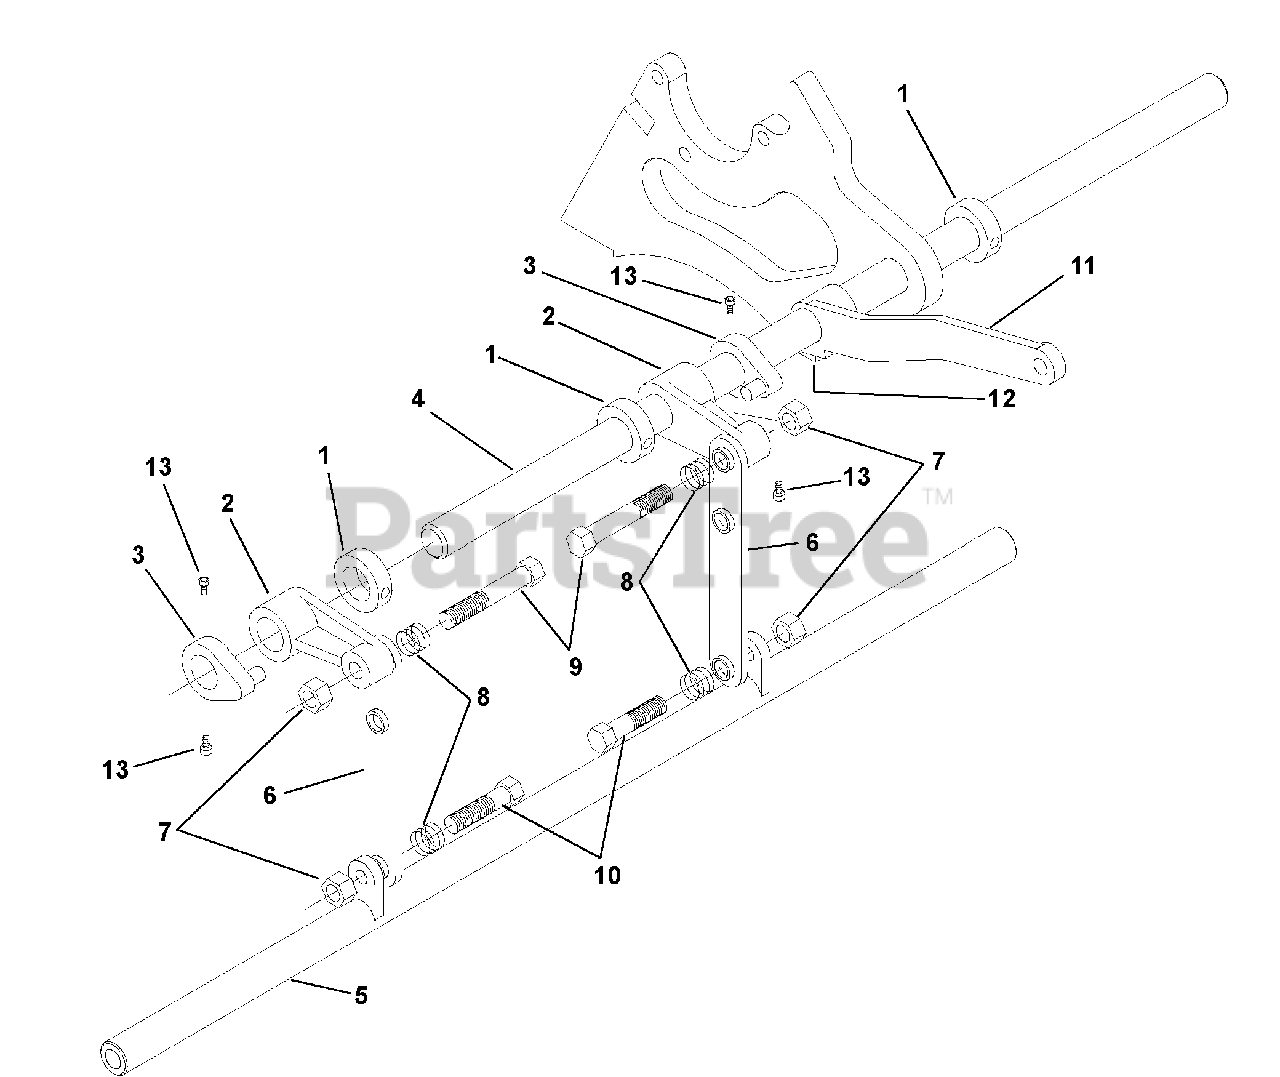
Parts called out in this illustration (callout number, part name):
2	Arm, Reel Lift
3	Collar, Lift
4	Shaft, Lift 25-Inch
5	Bar, Spacer 25-Inch
7	Nut, Hex .38-16
9	Cap Screw, Hex Head .38-16 x 1.75
10	Cap Screw, Hex Head .38-16 x 1.50
11	Lever, Reel Lift
12	Set Screw, Socket .312-24 x .25 Stainless Steel
13	Set Screw, Hex Socket Head .25 x .38 Grade 8
